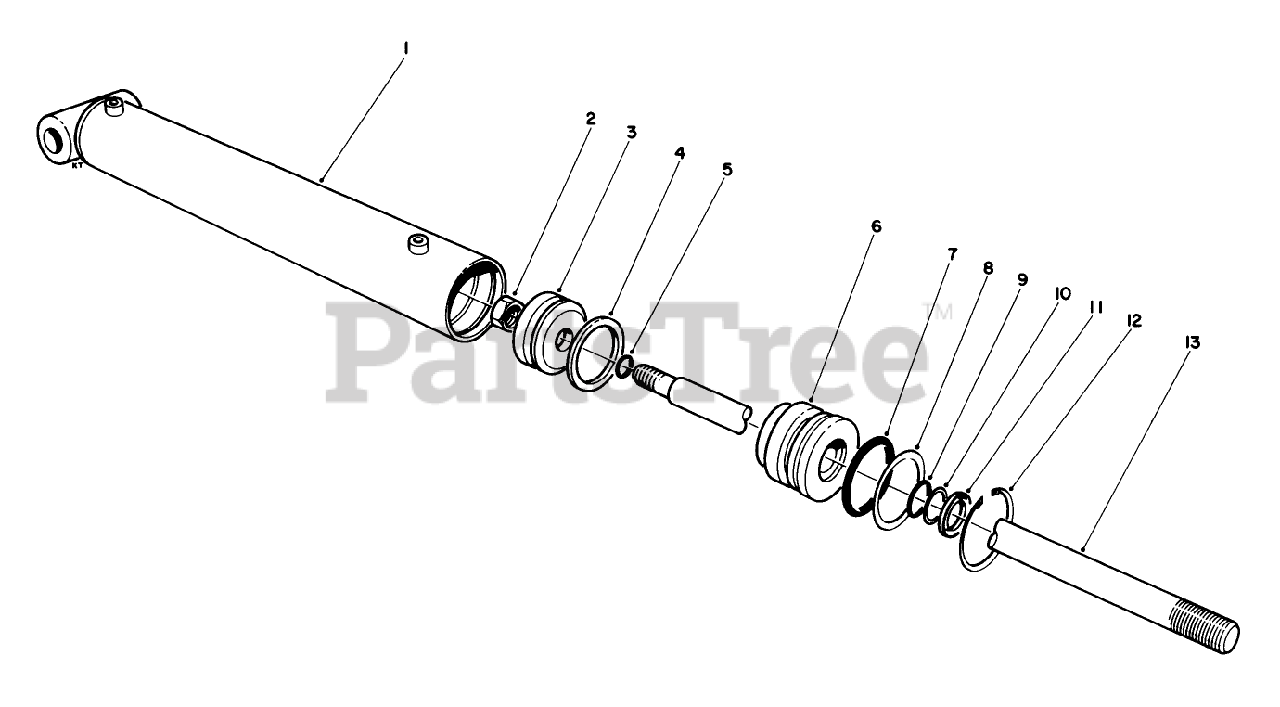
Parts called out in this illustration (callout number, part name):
2	LOCKNUT
3	PISTON
4	Uniring
5	O-Ring
7	O-Ring
8	Washer-Backup
9	0 Ring
10	Washer-Backup
11	Dust Seal
12	RING-RETAINING
13	SHAFT
